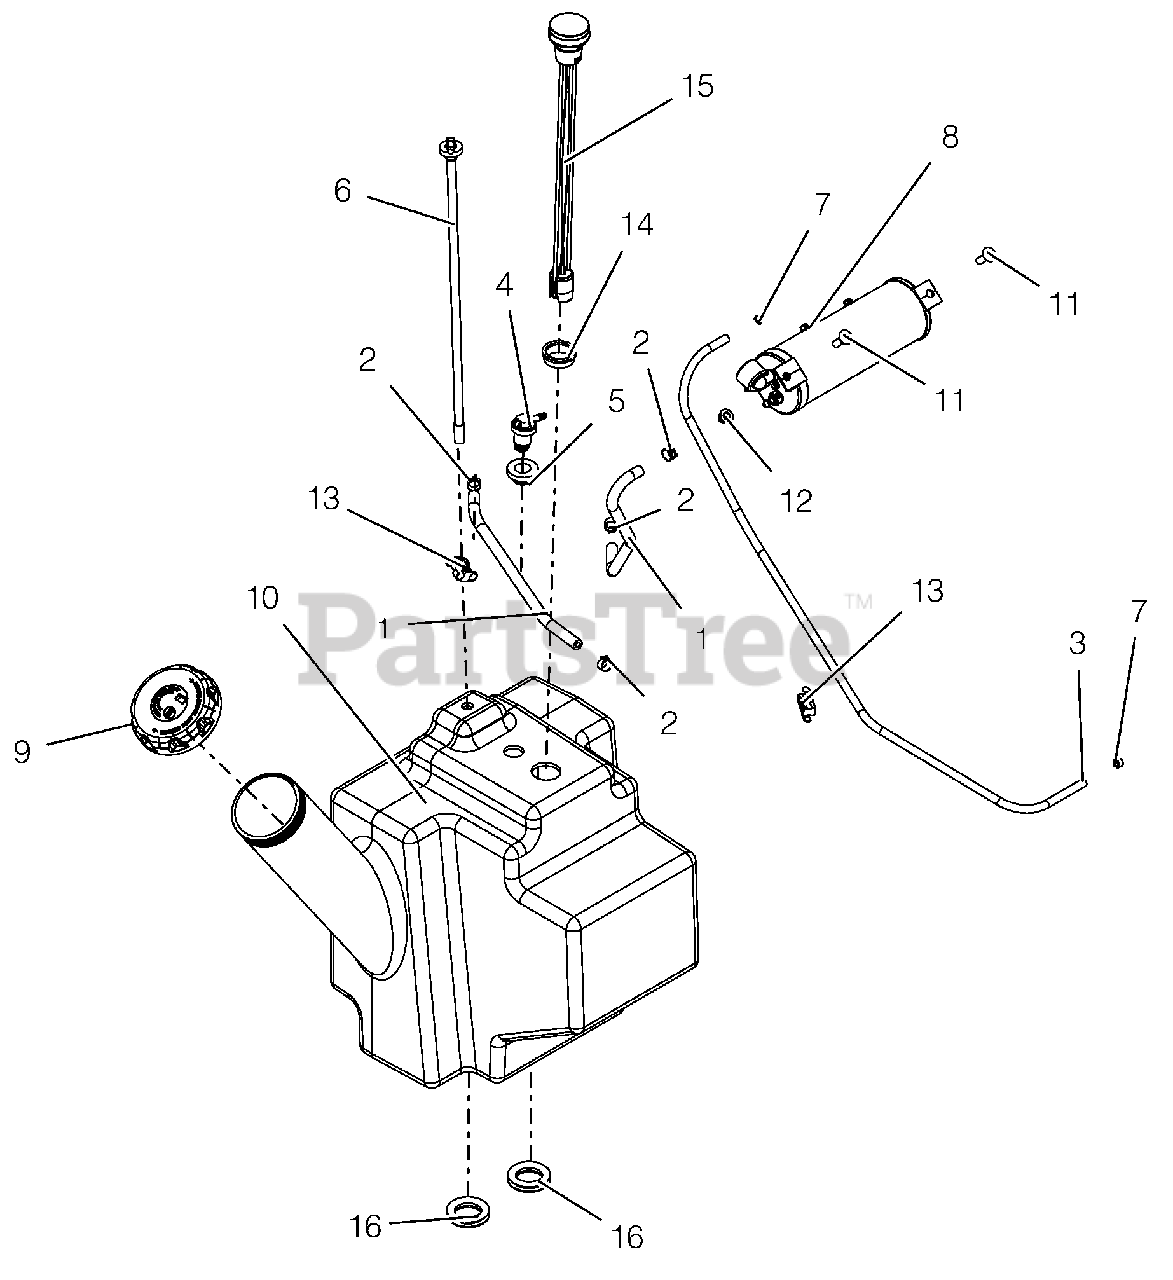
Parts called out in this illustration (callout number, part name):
1	HOSE, .25 LOW-PERM BULK GAS
2	CLAMP, FUEL LINE
3	HOSE, .188 LOW-PERM BULK GAS
4	VALVE, COMBINATION
5	GROMMET, REMOTE VENT NITRILE
6	ASS'Y, PROSTANCE FUEL PICK-UP
7	CLAMP-HOSE, SPRING .188
8	CANISTER, CARBON 9.3G CAP.
9	CAP, FUEL NONVENT AUTOLOCK
10	ASM, FUEL TANK
11	@BLT-RDHDSQNK .31-18X1.00 G5YZ
12	@NUT-LK-NYL-FLG .31-18 YWZC
13	CLIP, T, .38-.50
14	GROMMET, FUEL GAUGE
15	GAUGE, REMOTE FUEL SEALED 15"
16	GROMMET 1.25ID X 1.5OD
